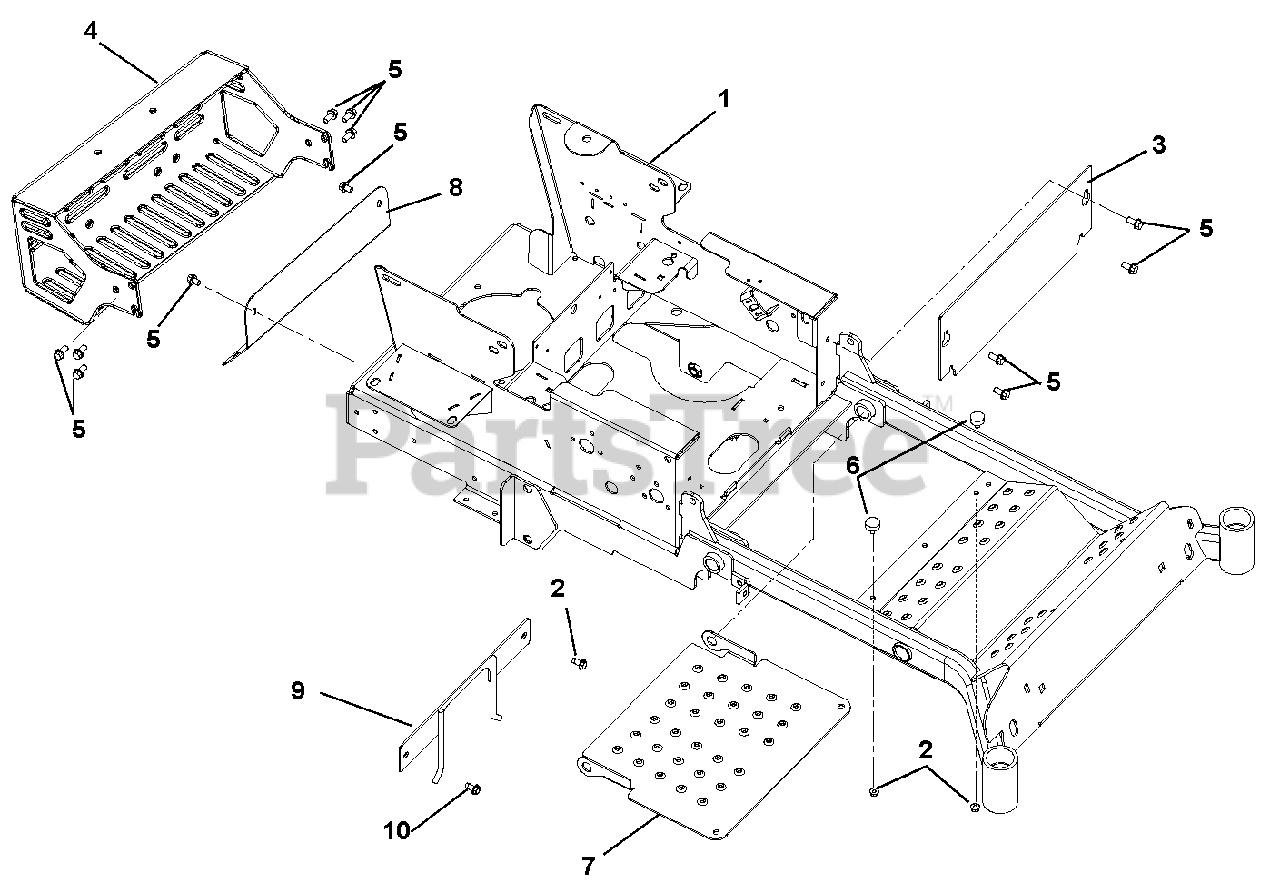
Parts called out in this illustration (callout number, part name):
1	Weldment, 44" – 48" HD Frame (991090, 082, 098, 099)
1	Weldment, 52" – 60" HD Frame (991083, 084, 100, 101)
2	Nut, Spin Lock Flange .312-18
3	Kick Plate
4	Bumper, Gravely HD
5	Screw, Tapping .38-16 x .75 Hex Washer Head
6	Bumper, Rubber
7	Panel, Inspection
8	Bracket, Heat Shield — Muffler
9	Weldment, PTO Belt Finger
10	Screw, Tapping .38-16 x .75 Hex Washer Head Thread
